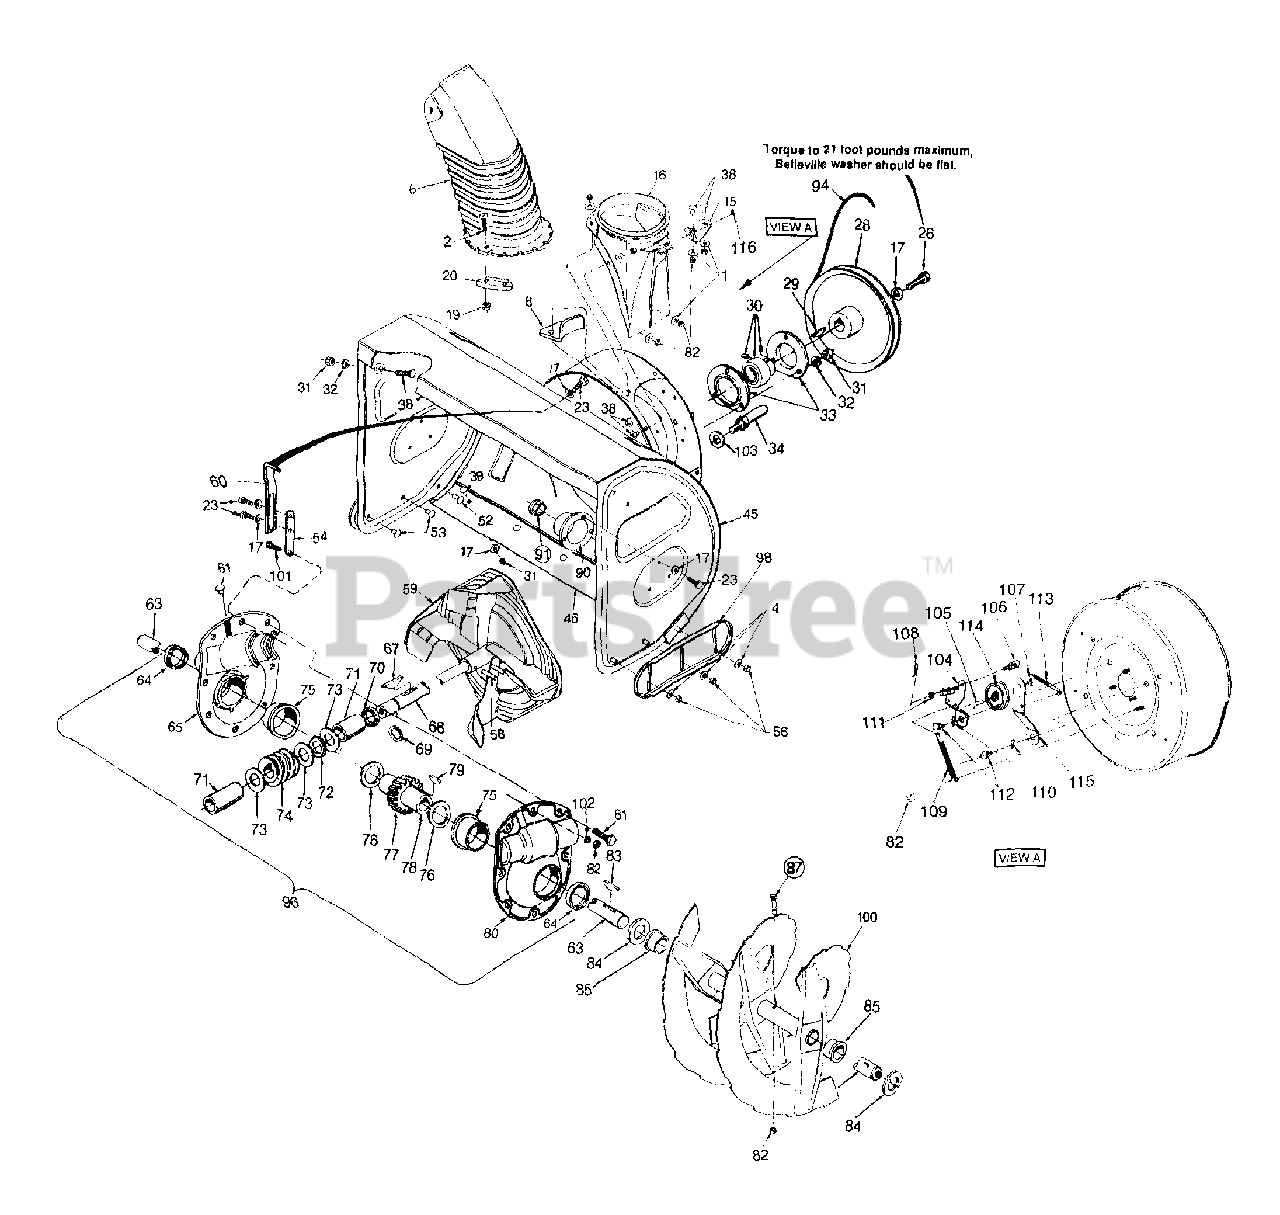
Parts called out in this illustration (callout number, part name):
1	Flat Washer .344 I.D. x .875 O.D.
2	Truss. Hd. Mach. Scr. 1/4-20 x .75
4	Bell. Washer
6	6" Lower Chute Remote Tilt
8	Chute Bracket
15	Chute Bracket
16	Chute Adapter
17	Bell. Washer .345 I.D. x .88 O.D. x .06
19	Hex Cent. L-Nut 1/4-20 w/Flange
20	Chute Flange Keeper
23	Hex Wash HD Self-Tap Scr 5/16-18 x .75
26	Hex Screw 5/16-18 x .75
28	1/2" V-Pulley .875 I.D. x 10.12 O.D.
29	#9 Hi-Pro Key 3/16 x 3/4 Dia. HT
30	Self-Aligning Bearing .875 I.D.
31	Hex Nut 5/16-18 Gr. 5
32	L-Wash 5/16 I.D.
33	Bearing Housing
34	Belt Keeper Studs 3/8-16 x 2.75
38	Carriage Bolt 5/16-18 x .75
46	Shave Plate 33"
52	Carriage Bolt 3/8-16 x 1.00 Gr. 5
53	Carriage Bolt 3/8-16 x .75" Lg.
54	Gear Housing Support Plate 1 x 3/16
56	Hex Jam Nut 3/8-16
58	Spring Spiral Pin Heavy 5/16 Dia. x 1.7
59	Blower Fan Ass'y
60	Gear housing Support Bracket 1 x 3/16
61	Barbed Plug
63	Spiral Axle -33"
64	Oil Seal 1.50 ID Garlock (76 x 6223)
65	Gear Housing Half - RH
67	#9 Hi-Pro Key 3/16 x 3/4 Dia. HT
68	Auger Drive Shaft
69	Snap Ring for .875 Dia. shaft
70	Oil Seal for .875 I.D. (76 x 6133)
71	Sleeve Bearing .875 I.D.
72	Thrust Bearing .88 I.D. x 1.44 O.D. x .078
73	Flat Washer .88 I.D. x 1.4 O.D. x .125
74	Worm Gear L.H. Double Thread
75	Flange Brg. 1.5 I.D. x 1.75 O.D. x .80
76	Flat Washer 1.5 I.D. x 2.0 O.D. x .03
77	Worm Gear LH Double Thread (Bronze)
78	Worm Gear Shaft
79	#91 Woodruff Key 1/4 x 3/4 Dia.
80	Gear Housing Half L.H.
81	Hex Flange Scr. 5/16-18 x .75
82	Hex Ins. L-Nut 5/16-18
83	#91 Woodruff Key 1/4 x 3/4 Dia.
84	Flat Wash.
85	Flange Bearing
87	Shear Bolt 5/16-18 x 1.75
90	Housing bearing 1.5 Dbl D
91	Flange Bearing w/flats
94	V-Belt 1/2 x 44 LG
96	Worm Gear Box Ass'y
100	RH Spiral Ass'y Serrated - 33"
100	LH Spiral Ass'y Serrated - 33"
101	Hex Scr 5/16-18 x 1.25
102	5/16 Sprg Wash.
103	3/8 Sprg Lock Wash.
104	Brkt Ass'y Brkt
105	Scr Hex Cap 3/8-24 x 1.5 Gr. 5
106	Adjustment Ferrule
107	Hex Ins L-Nut 3/8-24
108	Intern Cot-Pin 5/16 Dia.
109	Spr Extn .470 Dia. x 4.75 Lg
110	Wave Washer .66 ID x .88 O.D.
111	Fl-Wash SAE .34 x .68
112	Shld Scr .625 Dia. x .170 x .062
113	Rod Idler Auger
114	3.0 OD Flat Idler with Flanges
115	Brkt Idler Auger
116	Plastic Bushing .380 I.D.
